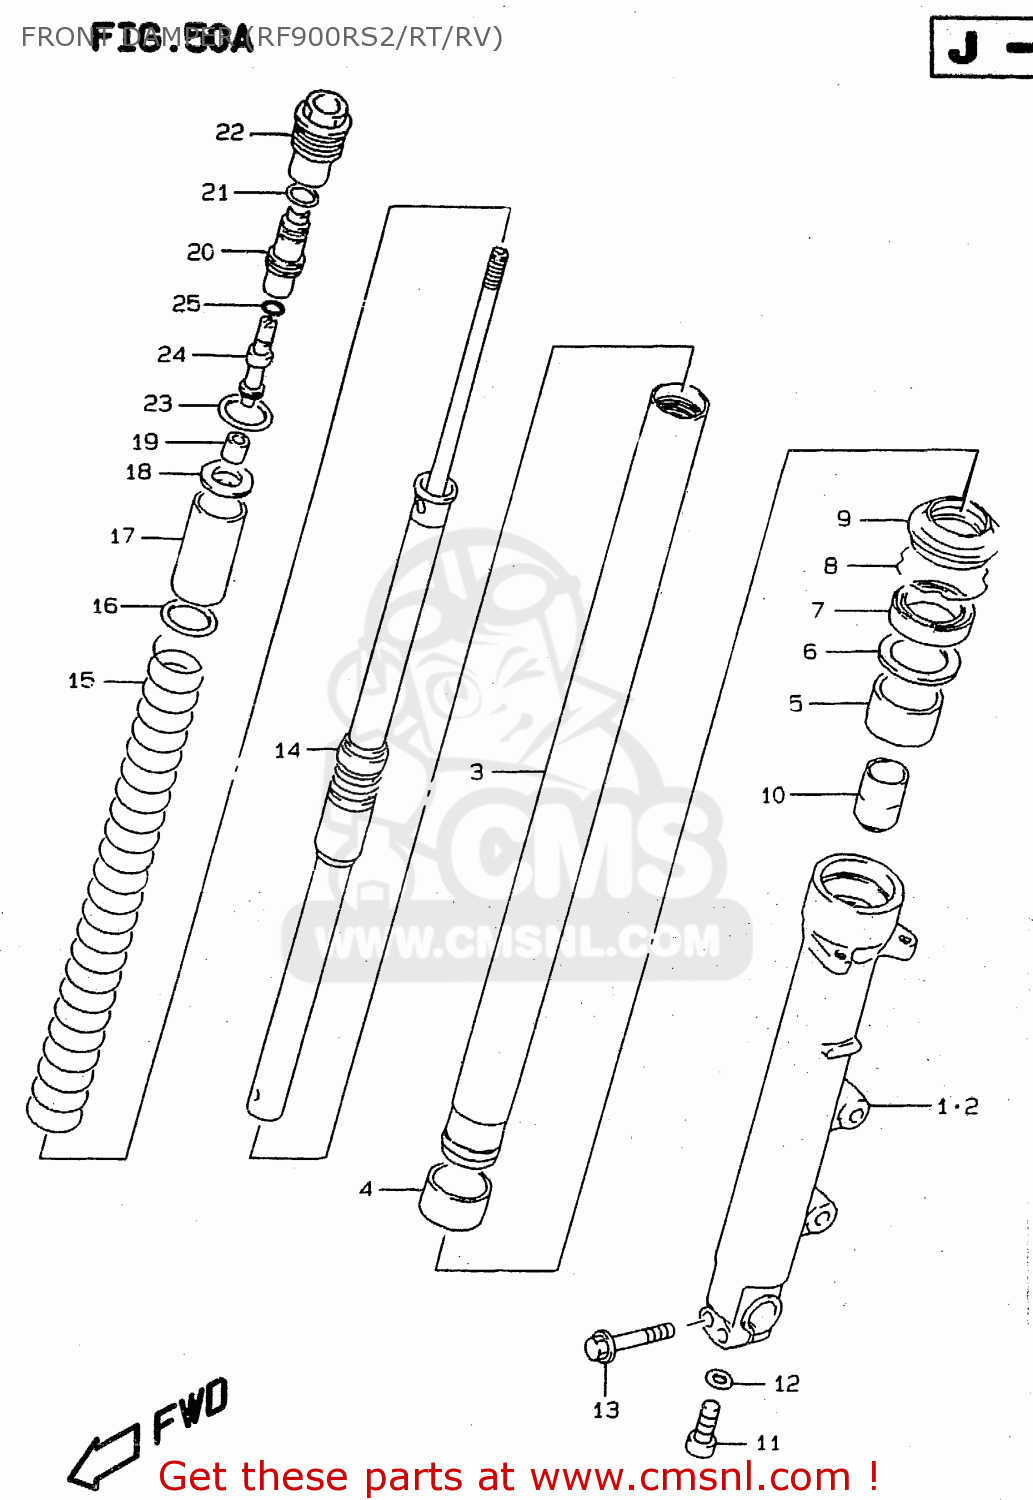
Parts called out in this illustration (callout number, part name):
1	TUBE,OUTER,R
2	TUBE,OUTER,L
3	TUBE,INNER
4	BUSH,SLIDE
5	BUSH,GUIDE
6	SPACER,SEAL
7	SEAL,OIL
8	CIRCLIP,FORK OIL SEAL
9	SEAL,DUST
10	PIECE,OIL LOCK
11	BOLT(8X27)
12	GASKET (NAS)
13	BOLT
14	DAMPER,FR
15	SPRING,MAIN
16	SEAT,SPRING LWR
17	COLLAR,SPRING(35X37X50)
18	SEAT,SPRING UPR
19	NUT
20	ADJUSTER,SPRING
21	O RING(D:2.5,ID:13.8)
22	BOLT,FORK
23	O RING
24	PIECE,ADJUSTER
25	O RING(D:1.9,ID:3.8)
